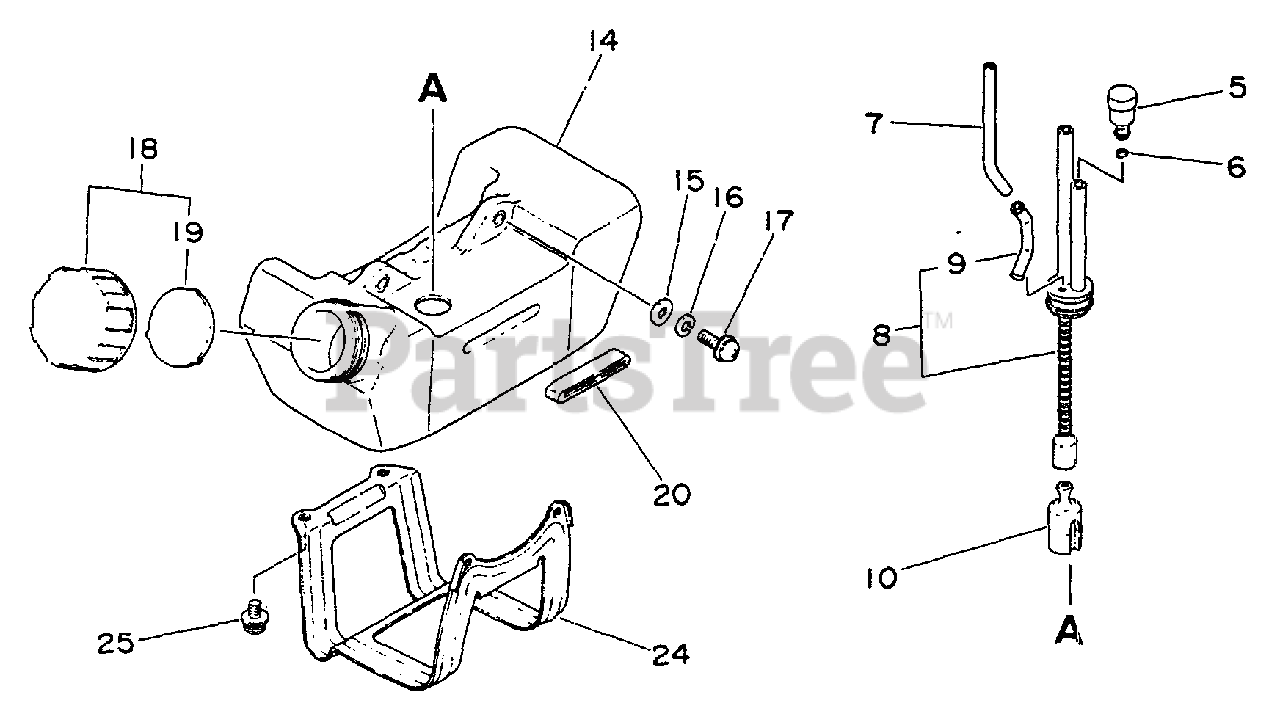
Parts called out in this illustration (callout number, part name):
5	VENT, FUEL TANK
6	CLIP - 5.5
7	PIPE - 3X6X75 -- CLEAR
8	FUEL PIPE KIT
9	CONNECTOR, PIPE
10	FILTER, FUEL
14	TANK, FUEL
15	WASHER - 5
16	LOCKWASHER - 5
17	SCREW - 5X16
18	CAP ASSY
19	GASKET, CAP
20	CUSHION, FUEL TANK
24	GUARD, FUEL TANK
25	SCREW - 5X10
